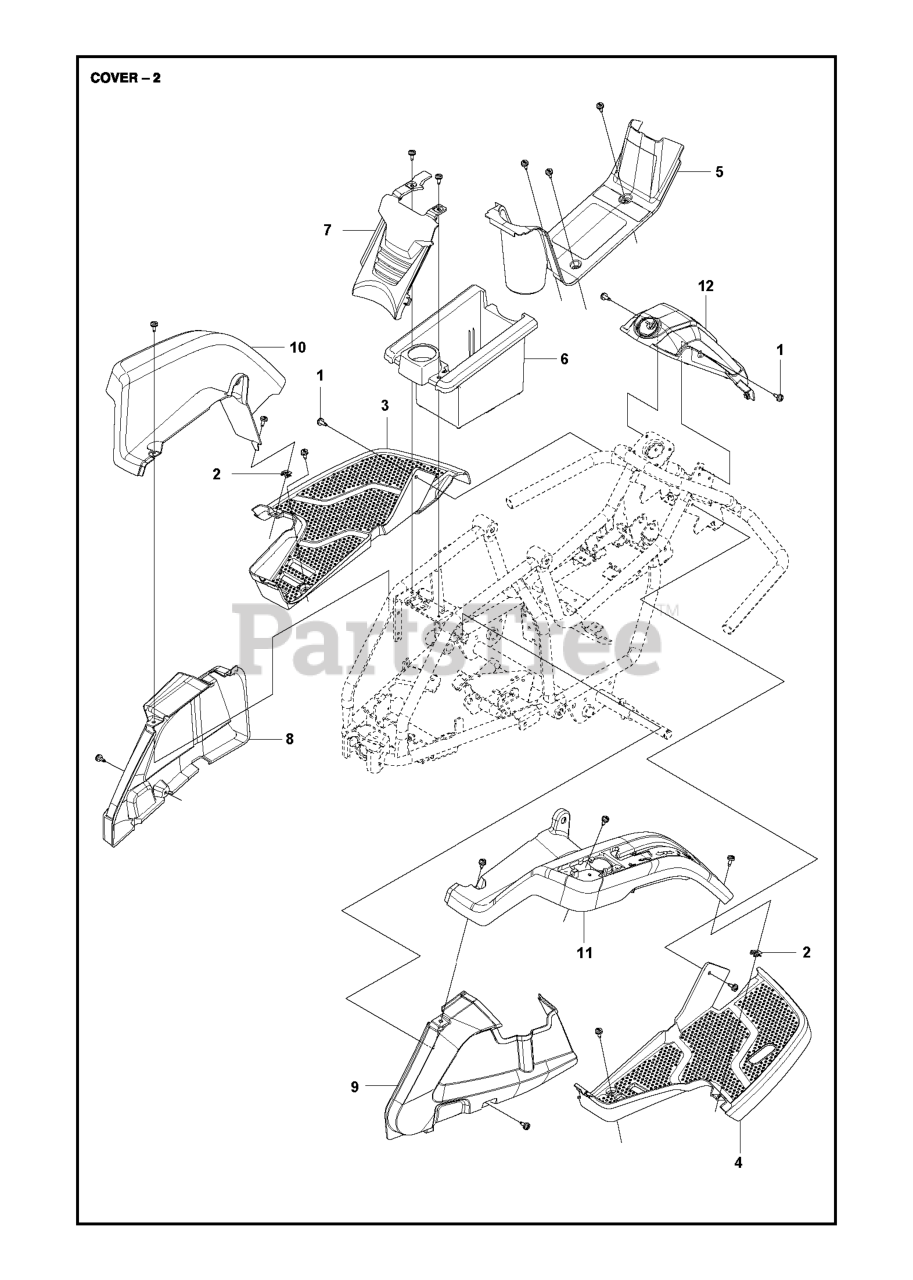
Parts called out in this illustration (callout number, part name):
3	FOOT PLATE
4	FOOT PLATE
6	BATTERY BOX
